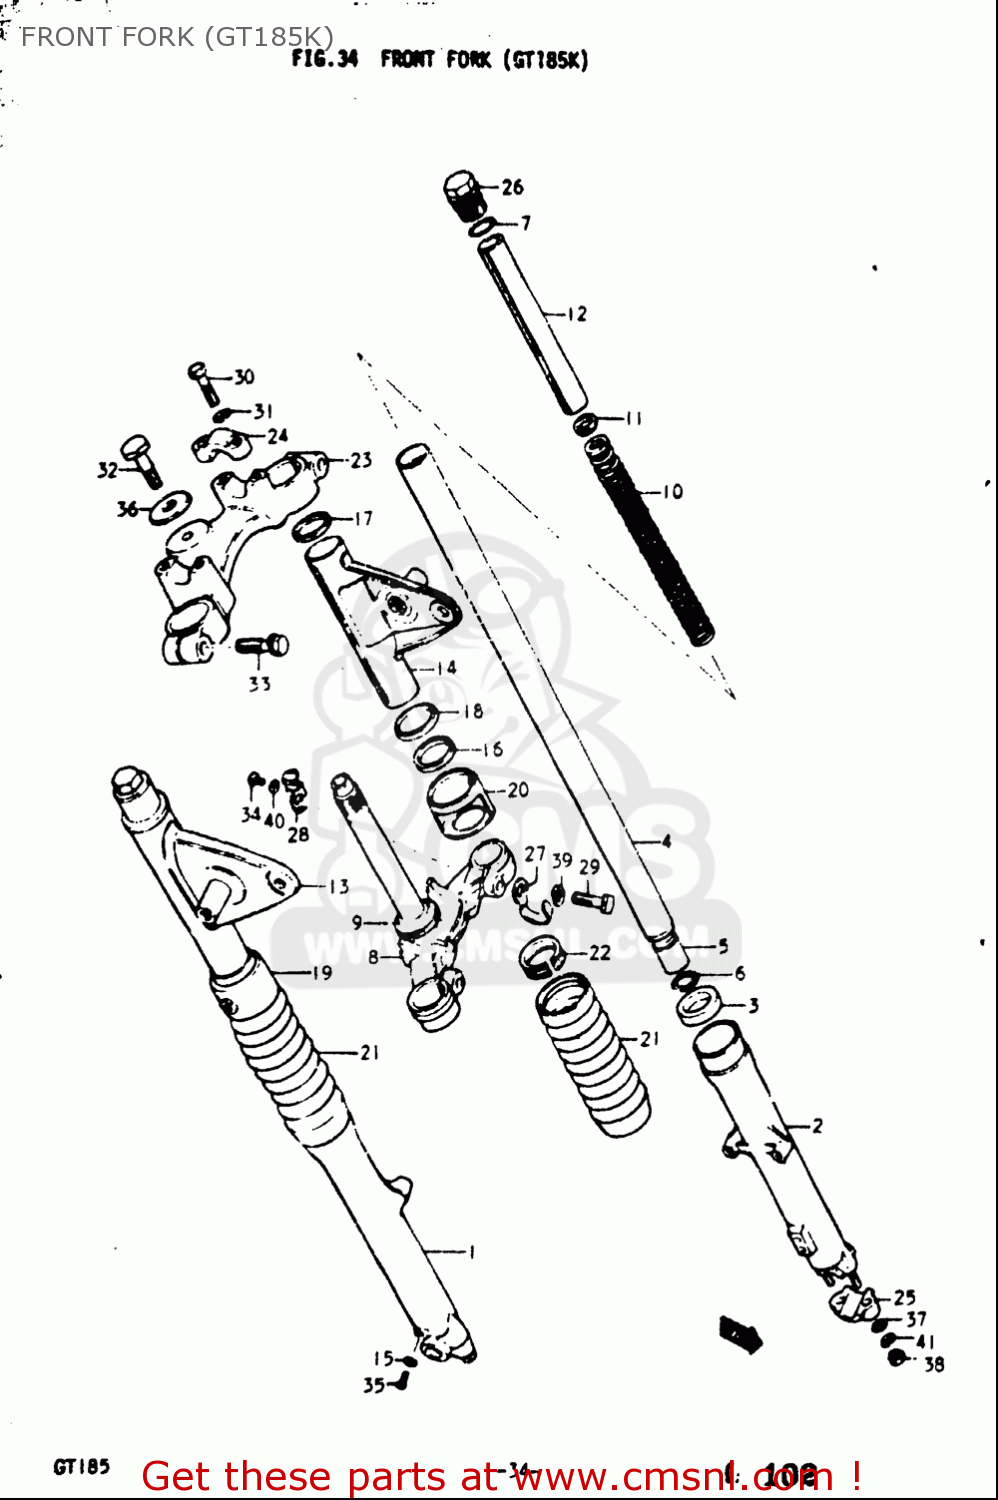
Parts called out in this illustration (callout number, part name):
3	SEAL,OIL
5	PISTON
6	RING,SNAP
7	O RING
9	RACE,STEERING OUTER LWR
11	GUIDE,SPRING COVER
15	GASKET,DRAIN,PLUG (NAS)
16	CUSHION,HEAD LAMP BRACKET
17	SEAT,HEADLAMP BRACKET
18	SEAT,HEADLAMP BRACKET
24	HOLDER,HANDLEBAR
26	BOLT,FR FORK
28	CLIP
30	BOLT
31	WASHER,LOCK
32	BOLT,FR FORK(10X33)
33	BOLT
34	SCREW
35	SCREW
36	WASHER
37	WASHER
38	NUT
39	WASHER,LOCK
40	WASHER,LOCK
41	WASHER,LOCK
